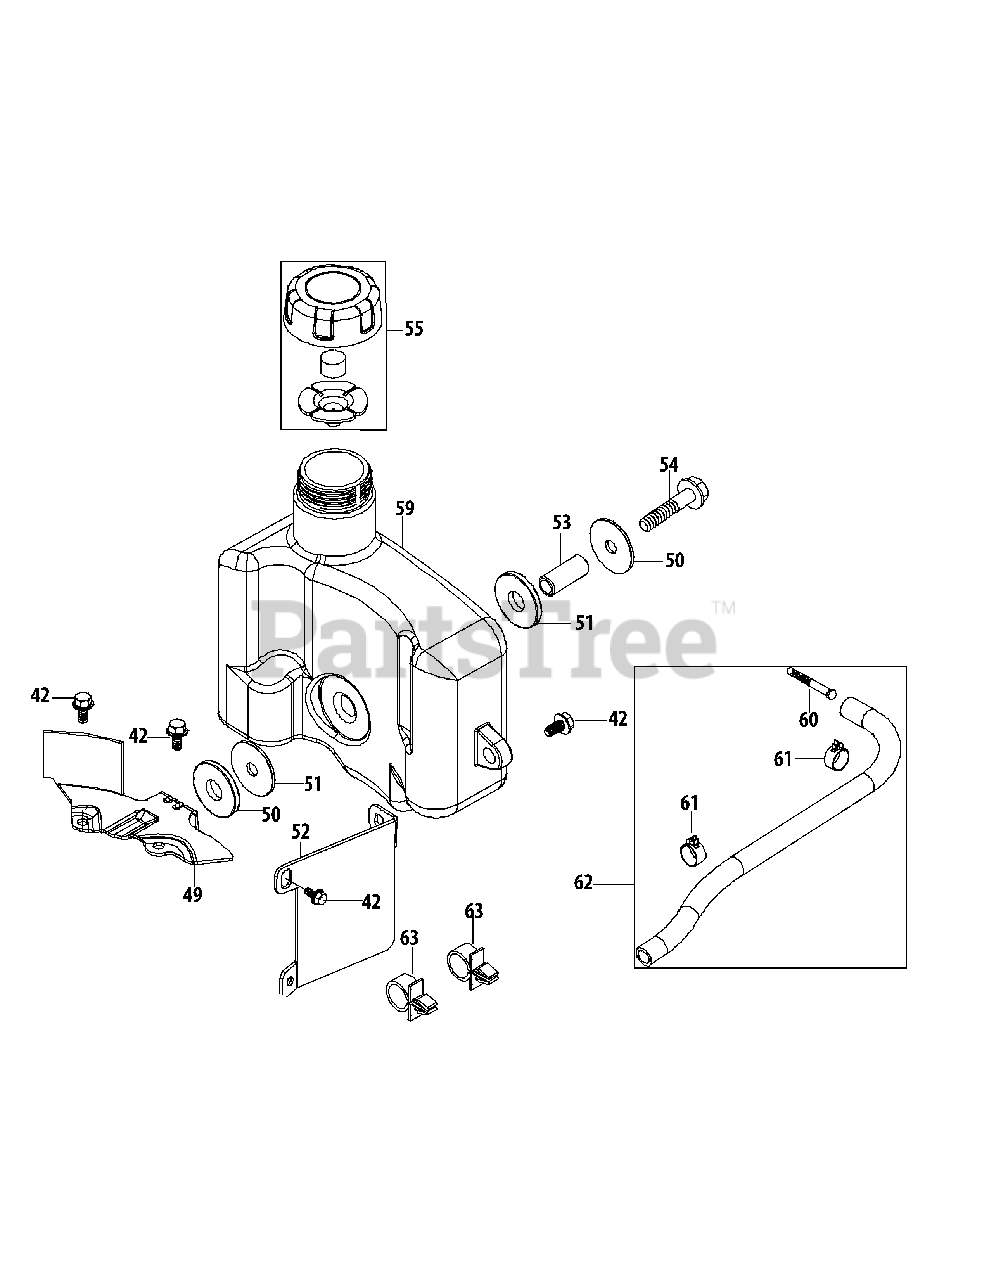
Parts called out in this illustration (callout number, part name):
42	Bolt M6X14
49	Fuel Tank Bottom Bracket
50	Fuel Tank Washer
51	Rubber Bushing
52	Fuel Tank / Label Bracket
53	Fuel Tank Bushing
54	Bolt M8X50
55	Fuel Cap Assembly
59	Fuel Tank Assembly
60	Fuel Filter
61	Fuel Hose Clamp
62	Fuel Line Kit
63	Plastic Support Clamp
